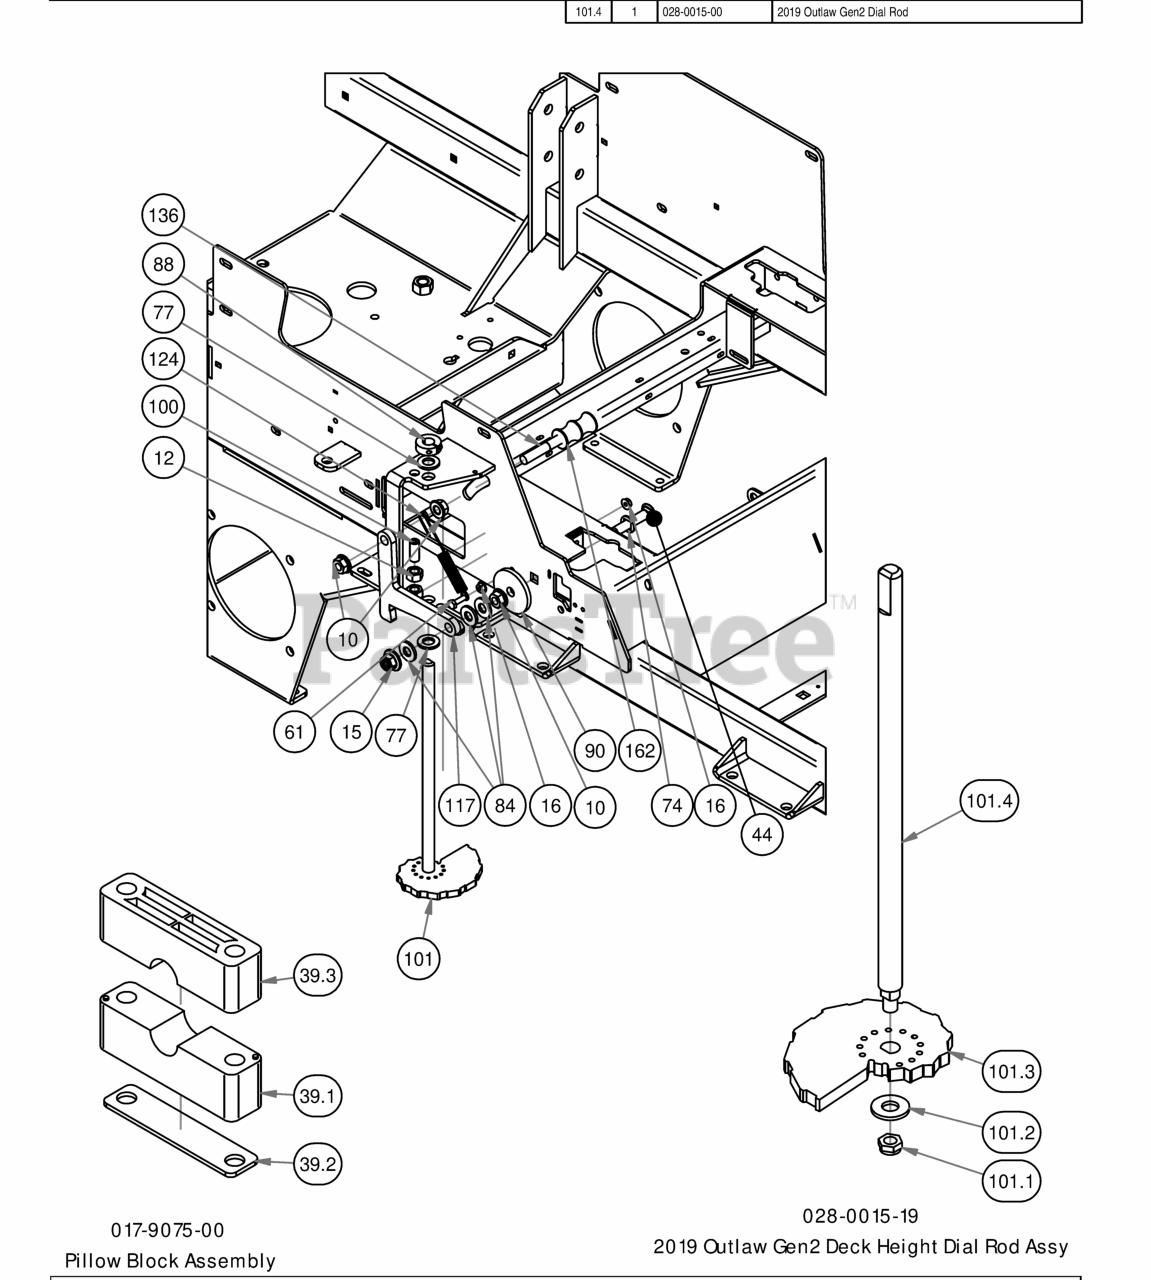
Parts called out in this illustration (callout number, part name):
10	1/2" Flange Nut
12	1/2" Hex Nut
15	1/2-13 Nylon Flange Nut
16	1/4-20 Hex Flange Nuts Zinc w/Serrations
39.1	Two Piece Pillow Block (Male)
39.2	Two Piece Pillow Block Strap
39.3	Two Piece Pillow Block (Female)
44	1/2 x 2-1/2 Carriage Bolt
61	1/4-20 x 1-1/4 GR 5 Hex Bolt
74	.517 Square Hole Round Washer
77	.630 ID Plastic Washer
84	.505 Nylon Spacer
88	5/8" Split Collar
90	MZ Deck Idler Spacer
100	Dial Rod Plunger
101	2019 Outlaw Gen2 Deck Height Dial Rod Assy
101.1	3/8-24 Nylon Insert jam locknut
101.2	3/8" Flat Washer
101.3	2019 Deck Height Cam
101.4	2019 Outlaw Gen2 Dial Rod
117	2019 Outlaw Deck Travel Lock
124	Brake Spring
136	Seat Bracket Pin
162	Travel Lock Rubber Grip
